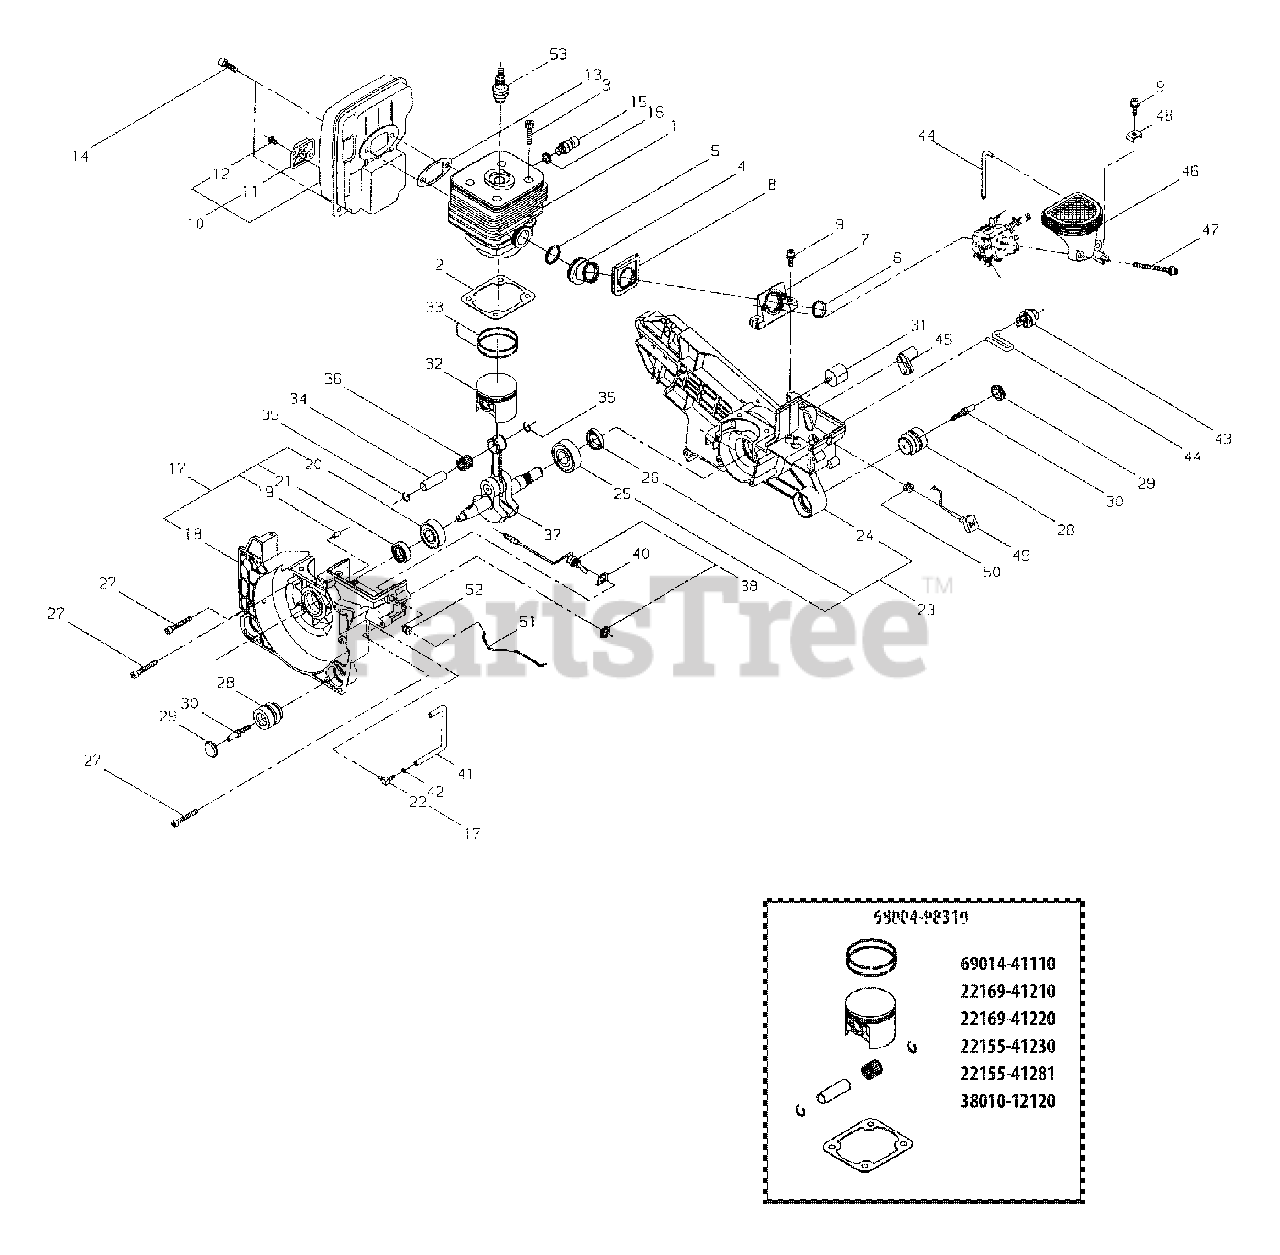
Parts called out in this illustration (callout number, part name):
1	CYLINDER
2	GASKET
3	BOLT
4	BOOT
5	SPRING
6	SLEEVE
8	SEAL
9	SCREW - 5X14
10	MUFFLER ASSY
11	TAIL PLATE
12	SCREW - 5X8
13	GASKET
14	SCREW - 6X20
15	VALVE, DECOMPRESSION
16	GASKET
17	CRANKCASE ASSY - LEFT
18	CRANKCASE ASSY - REAR
19	PIN - LOCATING
20	BEARING, BALL - 6202
21	SEAL, OIL
22	CONNECTOR, PIPE
23	CRANKCASE ASSY - RIGHT
24	CRANKCASE - RIGHT
25	BEARING, BALL - 6203C3
26	SEAL, OIL
27	BOLT - 5X35
28	CUSHION
29	PLUG
30	BOLT
31	CUSHION
32	PISTON
33	RING, PISTON
34	PIN, PISTON
35	RING, RETAINING
36	BEARING, NEEDLE
37	CRANKSHAFT ASSY
38	SWITCH ASSY
40	SWITCH PLATE
41	PIPE - IMPULSE
42	CLIP
43	BULB, PURGE
44	TUBE
45	GROMMET, CABURETOR
46	ELBOW
49	ROD, CHOKE
50	GROMMET
51	ROD, THROTTLE
52	GROMMET
53	SPARK PLUG -- BPMR-7A
68004-98310	PISTON ASSY
